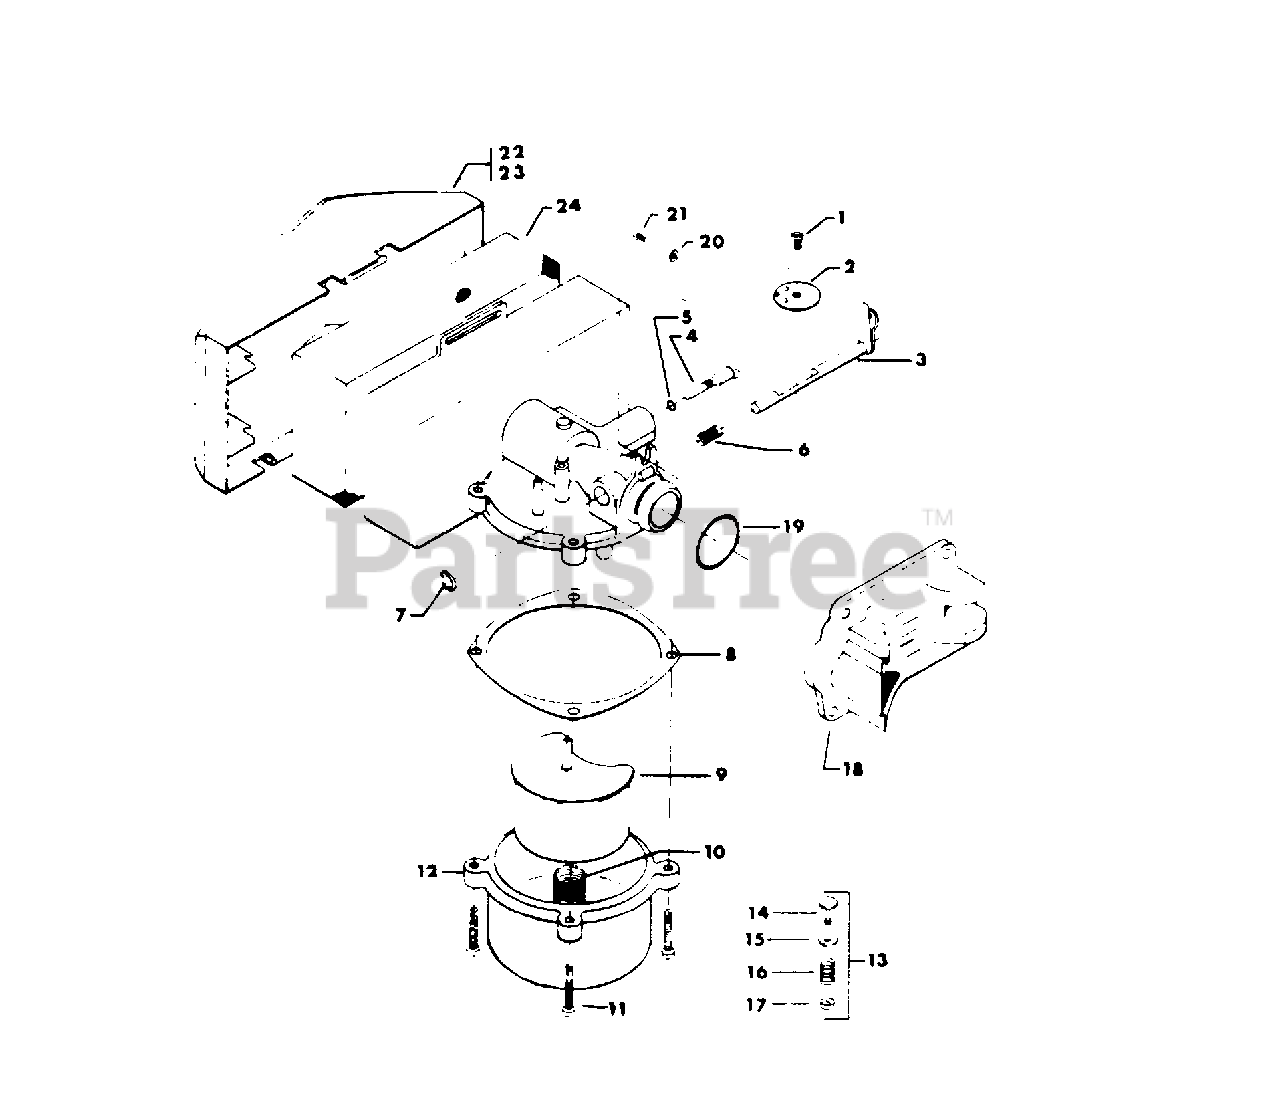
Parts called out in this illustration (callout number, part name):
1	Screw, disk
2	Disk, throttle
3	Throttle Shaft
4	Screwier, Alt. Adj.
6	Spring, Throttle
7	Clip, Ring
8	Gasket, Bowl
10	Spring, Float
11	Screw, Bowl
14	Valve Stem
15	Valve Seat
16	Valve Spring
17	Valve Keeper
18	Reed Plate
21	Screw, Mtg.
22	Cover, Filter (Deluxe)
23	Cover, Filter (C.D.)
24	Element
